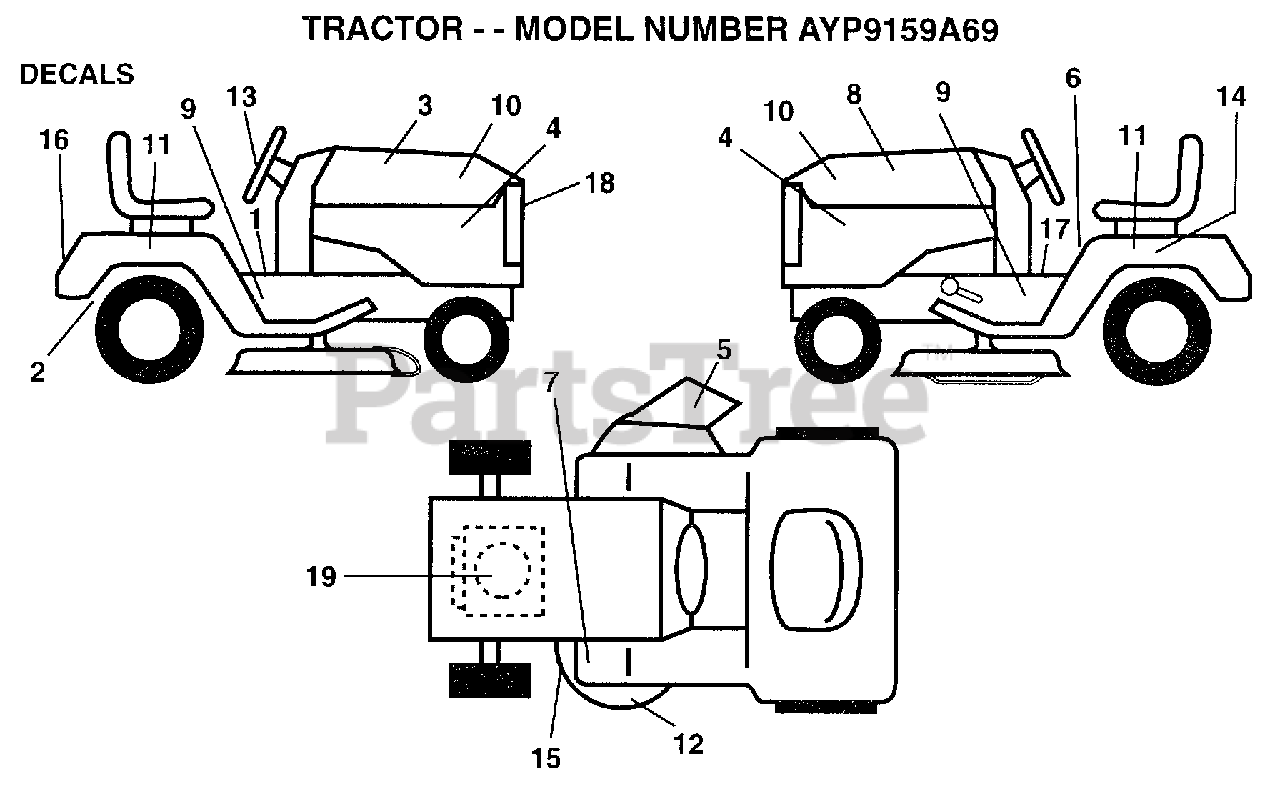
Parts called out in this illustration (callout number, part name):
2	DECAL DRAWBAR LH
3	DECAL HOOD RH
4	DECAL.PNL.SD.VANG
5	DECAL DECK MULCH
6	DECAL
8	DECAL HOOD LH
9	"DECAL.CHASSIS.42"""
10	NAMEPLATE.HD.WIZA
11	DECAL.FENDER.WIZ
12	DECAL DECK WIZ +
13	DECAL STEER WHL
14	DECAL.BTRY.DANGER
15	DECAL
17	DECAL SADLE HYDRO
18	DECAL.LENS.WIZARD
19	DECAL B&S ENGINE 15.5 HP VANG
